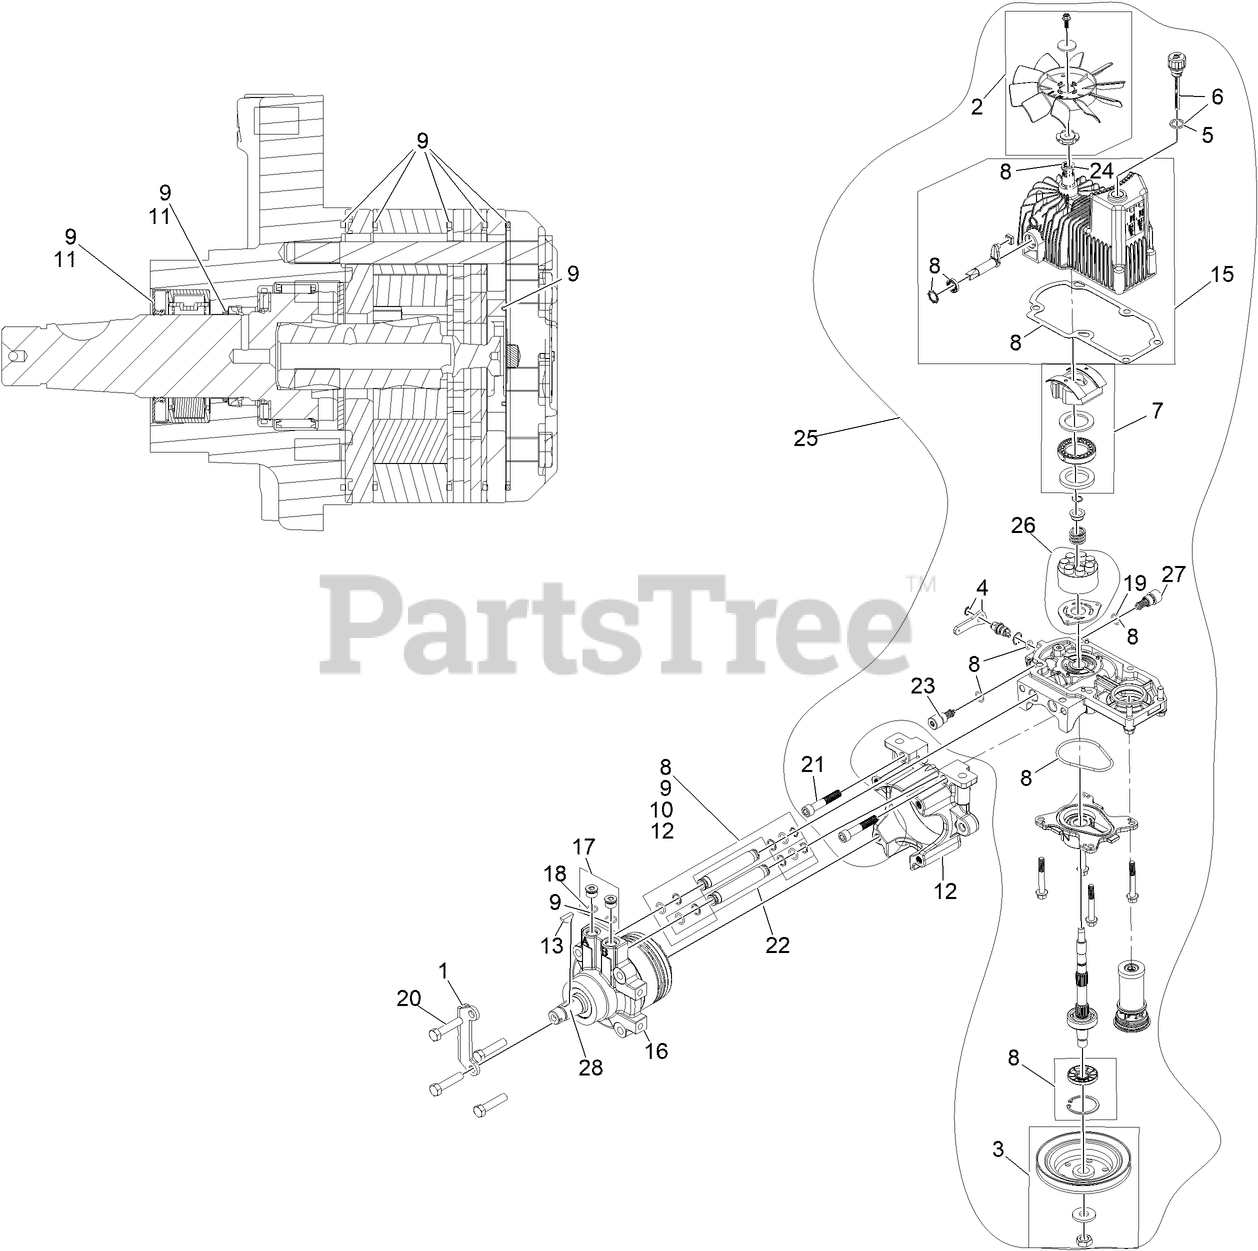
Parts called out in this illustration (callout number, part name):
1	PLATE, HORSE SHOE MOUNT
2	KIT, 7.8 IN FAN
3	PULLEY KIT
4	HANDLE-BYPASS VALVE, HYDRO
5	GASKET-DIPSTICK, HYDRO
6	DIPSTICK-HYDRO W/GASKET
7	SWASH BLOCK KIT
8	KIT, PUMP SEAL
9	MOTOR SEAL KIT
10	TUBE SEAL KIT
11	OUTPUT SHAFT SEAL KIT
12	NOSE CUP-UHT
13	KEY-WOODRUFF
15	KIT, HOUSING-HYDRO RH
16	HYD MOTOR,280CC RH SEALED
17	MAGNETIC PLUGS SERVICE KIT
18	O-RING
19	O-RING-CHECK VALVE
20	SCREW HH
21	SCREW-HSH
22	HYDRAULIC TUBE KIT
23	SHOCK VALVE, 16CC HYDRO
24	SEAL-FAN DRIVE
25	KIT, PUMP SECTION 16CC RH
26	KIT - 16CC PORT PLATE,ROTATE GRP
27	SHOCK VALVE ORIFICED 3300
28	OUTPUT SHAFT- TL UHT MOTOR
99	PULLER-PULLEY
